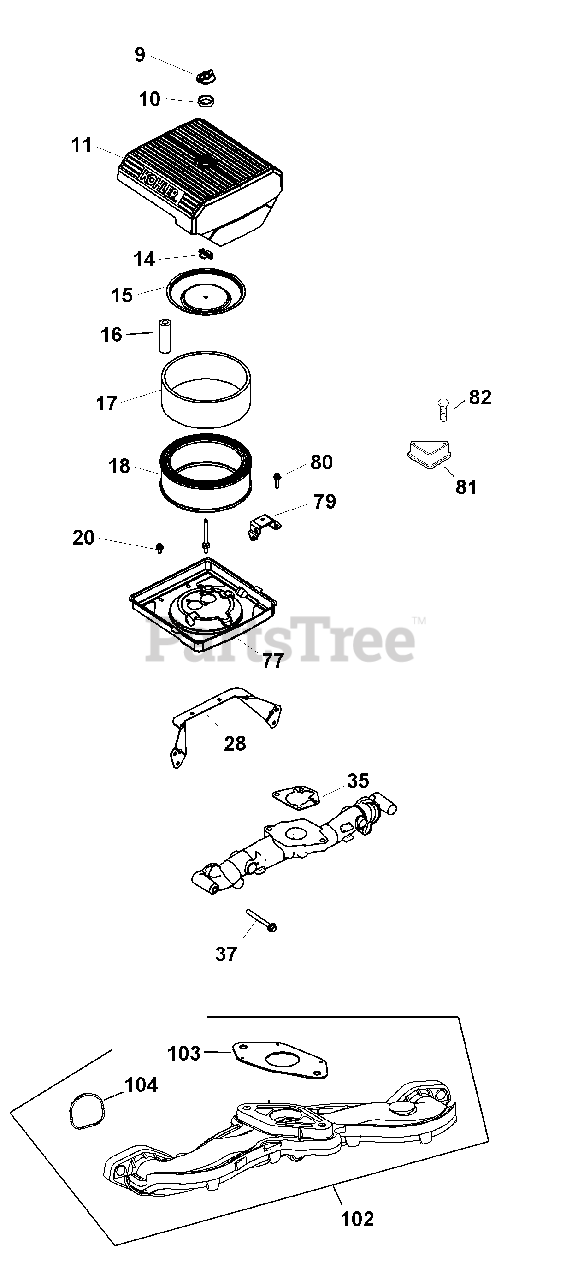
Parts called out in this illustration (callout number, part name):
15	Cover, Inner Air Cleaner
16	Seal, Inner Air Cleaner
17	Element, Precleaner (Low)
18	Element, Air Cleaner & Precleaner
20	Screw, Thread Forming
28	Bracket, Air Cleaner Base
35	Gasket, Air Cleaner Base
37	Screw, Flg M6X1.0X40
77	Kit, Air Cleaner Base
79	Bracket, Air Cleaner
80	Screw, Flg Thd Frm M6X1.0X16
81	Cover, Blower Housing
82	Screw, Hex Washer Hi-Lo
102	Kit, Intake Manifold
103	Gasket, Carburetor
104	O-Ring, Intake Port
